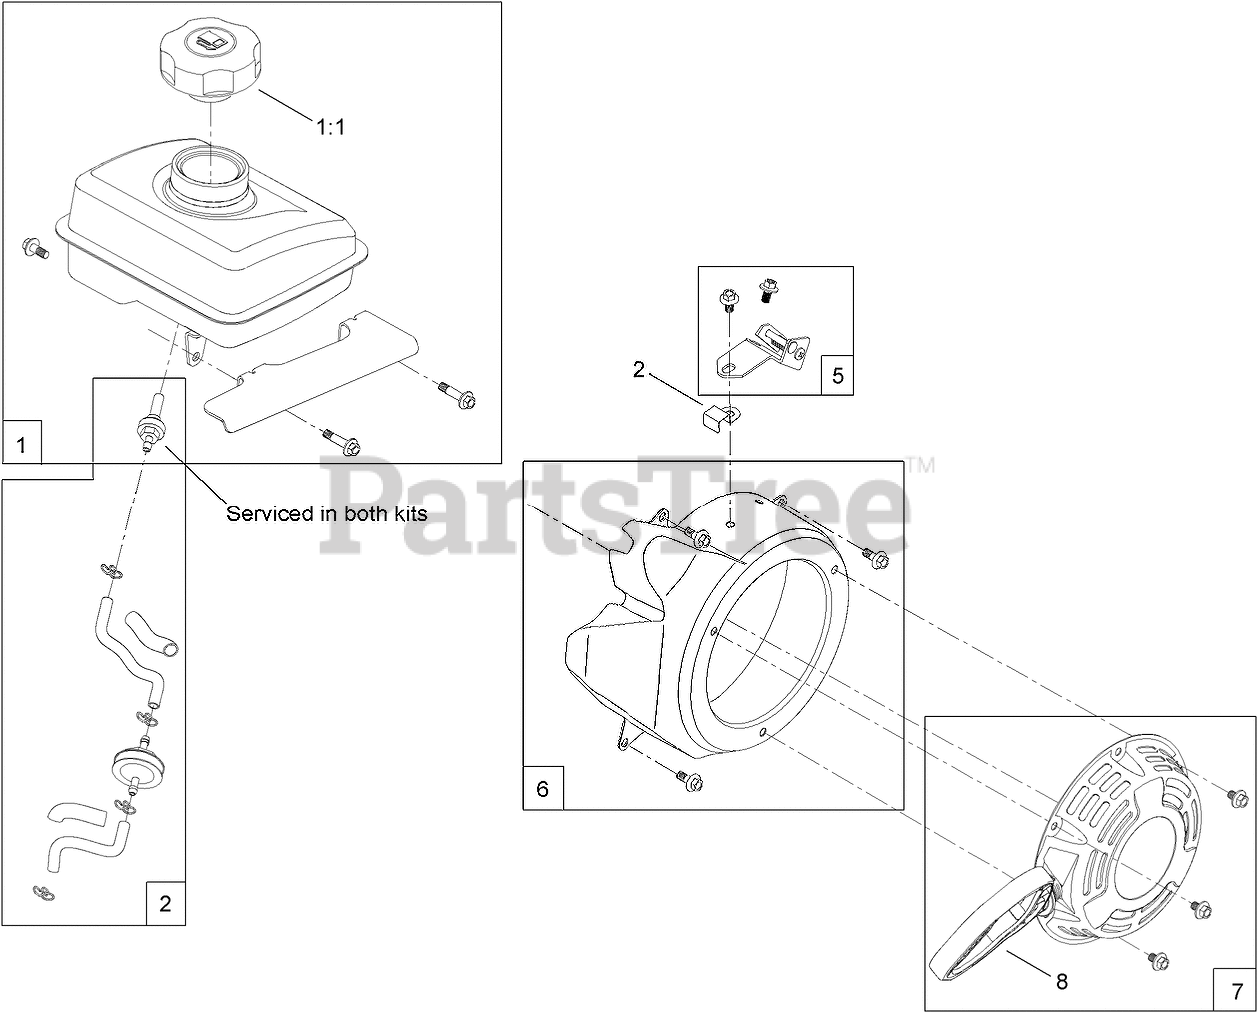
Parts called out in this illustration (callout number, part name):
1	FUEL TANK AND CAP KIT
1:1	CAP-FUEL
2	FUEL LINE KIT
5	GOVERNOR KIT
6	BLOWER SHROUD KIT
7	RECOIL ASM KIT
8	MITTEN GRIP KIT
